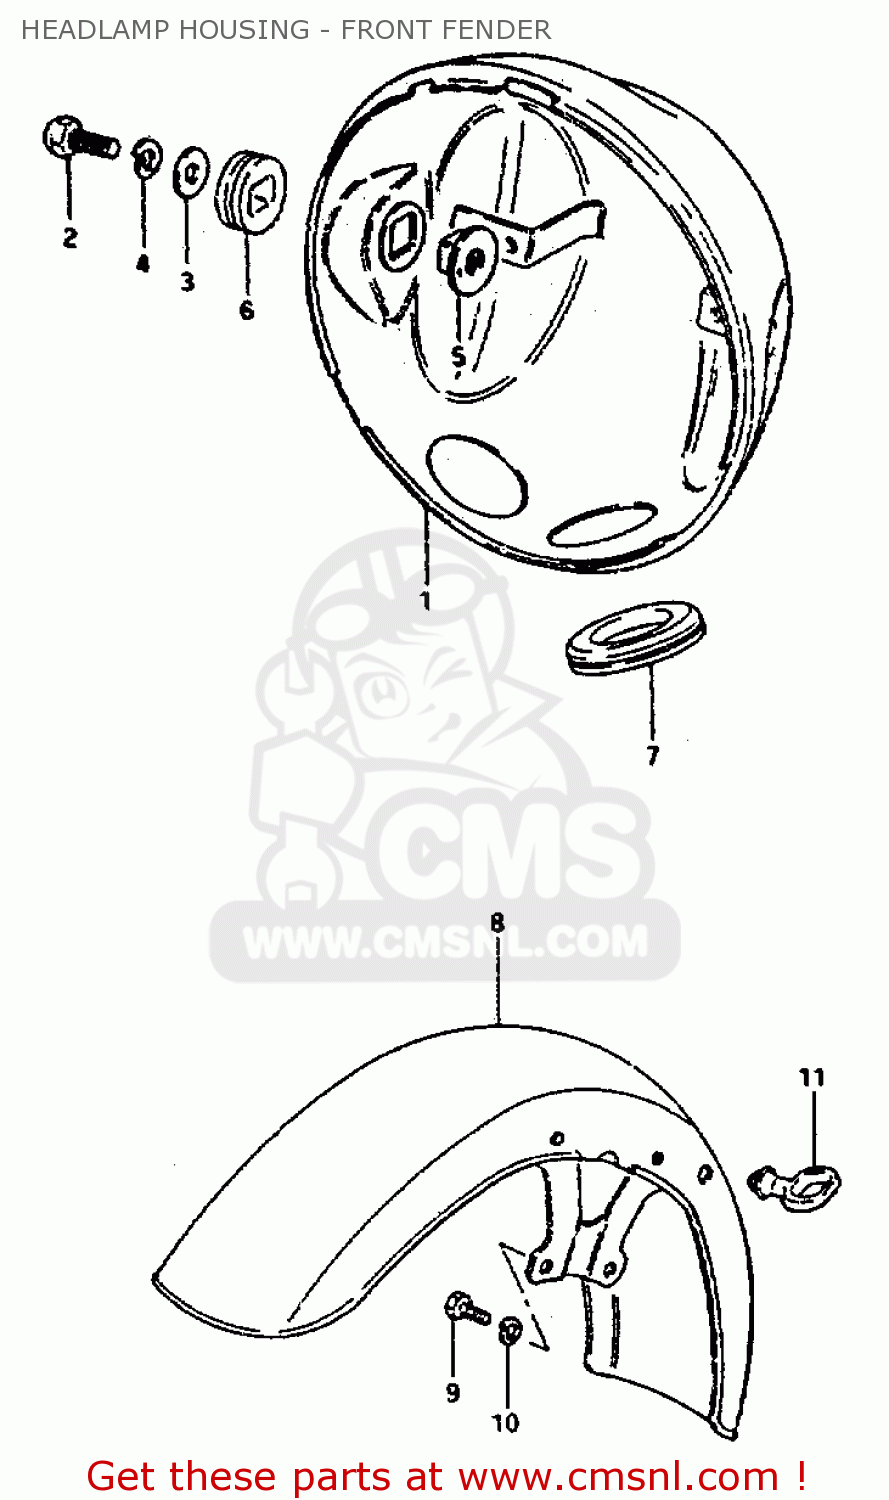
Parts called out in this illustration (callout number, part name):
1	HOUSING,HEADLAMP
2	BOLT
3	WASHER
4	LOCK WASHER
5	SPACER,HEADLAMP HOUSING
6	CUSHION,HEADLAMP HOUSING
7	GROMMET,HEADLAMP HOUSING
8	FENDER,FRONT
9	BOLT
10	LOCK WASHER
11	GUIDE,CABLE
